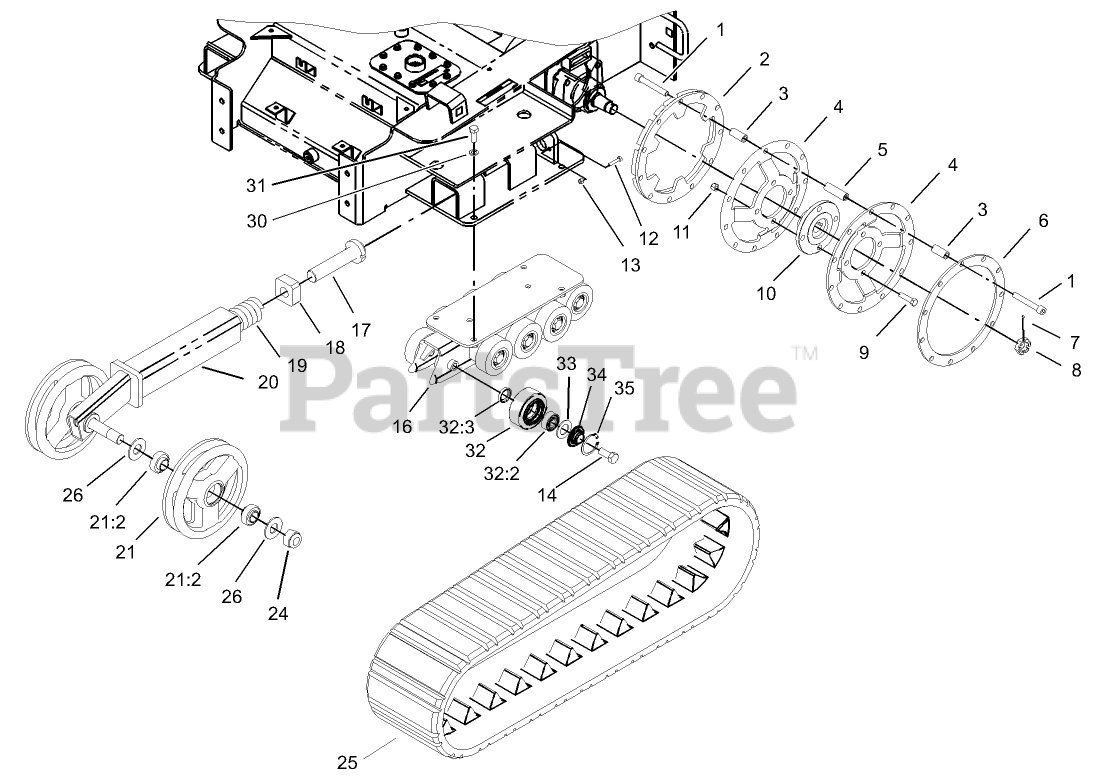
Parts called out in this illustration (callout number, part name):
1	SCREW-HSH
2	Brake Rim ASM,
3	SPACER-WHEEL, DRIVE
4	DRIVE WHEEL ASM
5	SPACER-WHEEL, DRIVE
6	RING-WHEEL, DRIVE
7	PIN-COTTER
9	SCREW-HH
10	HUB-WHEEL, DRIVE
11	NUT-LOCK, NI
12	SCREW-HH
13	NUT-LOCK, NI
14	SCREW-HH
16	Track Guide ASM
17	BOLT-TENSIONER
18	BLOCK-TENSIONER
19	SPRING-COMPRESSION
20	TENSIONER ARM ASM
21	Tensioner Wheel ASM
21:2	Bearing-Ball
24	NUT-HEX, NI
25	TRACK
26	Washer-Flat
30	WASHER-LOCK
31	SCREW-HH
32	Road Wheel ASM
32:2	BEARING
32:3	SEAL-OIL
33	Gasket-Bogie
34	CAP-WHEEL, BEARING
35	RING-SNAP, INTERNAL
